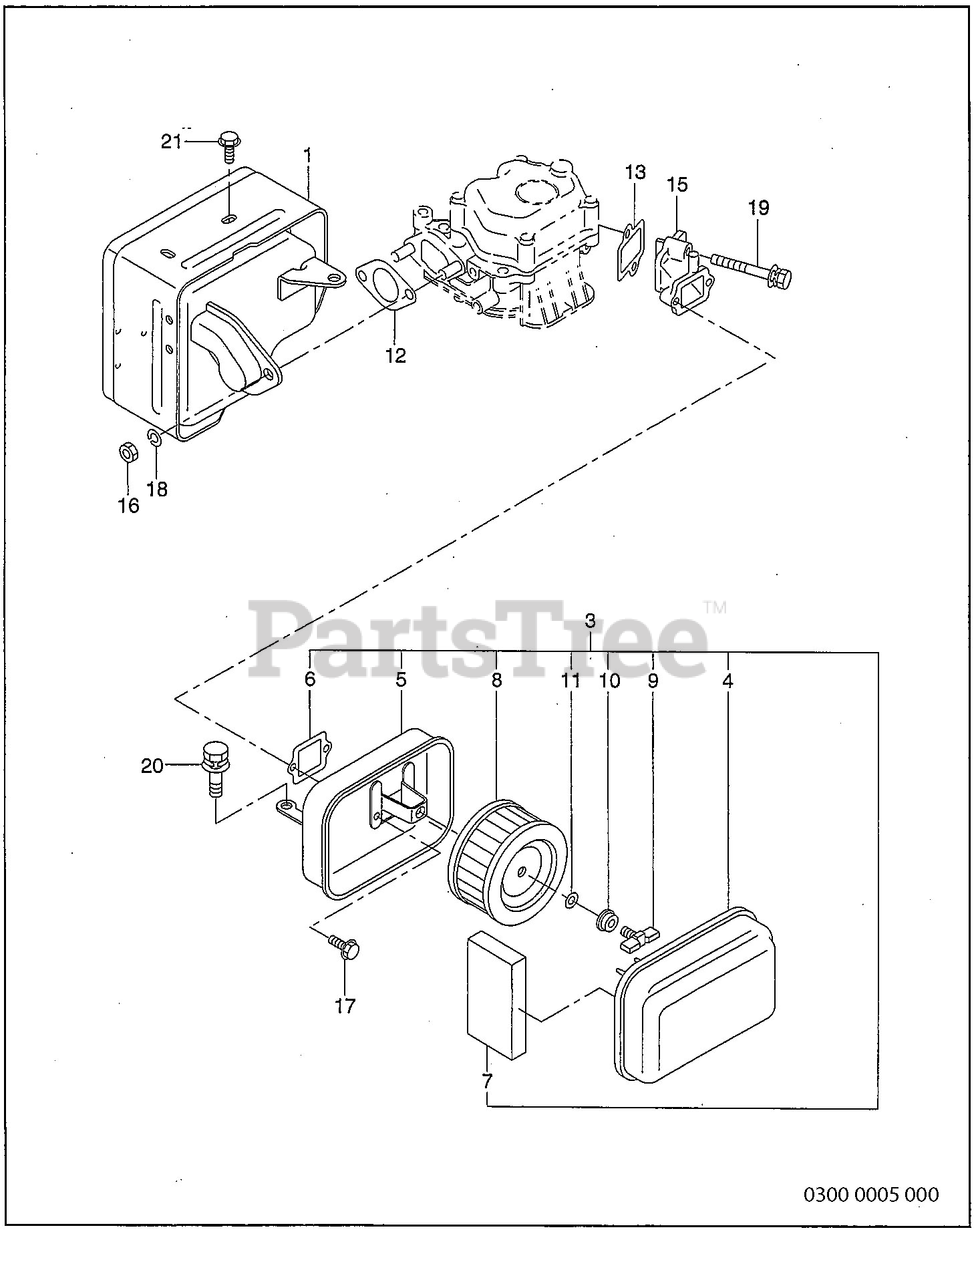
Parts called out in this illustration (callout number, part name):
3	AIR CLEANER ASSY
5	BACK PLATE ASSY
12	GASKET, EXHAUST
13	GASKET, INTAKE
15	INTAKE MANIFOLD
17	BOLT and WASHER ASSY
19	BOLT and WASHER ASSY
20	BOLT and WASHER ASSY
21	BOLT and WASHER ASSY
